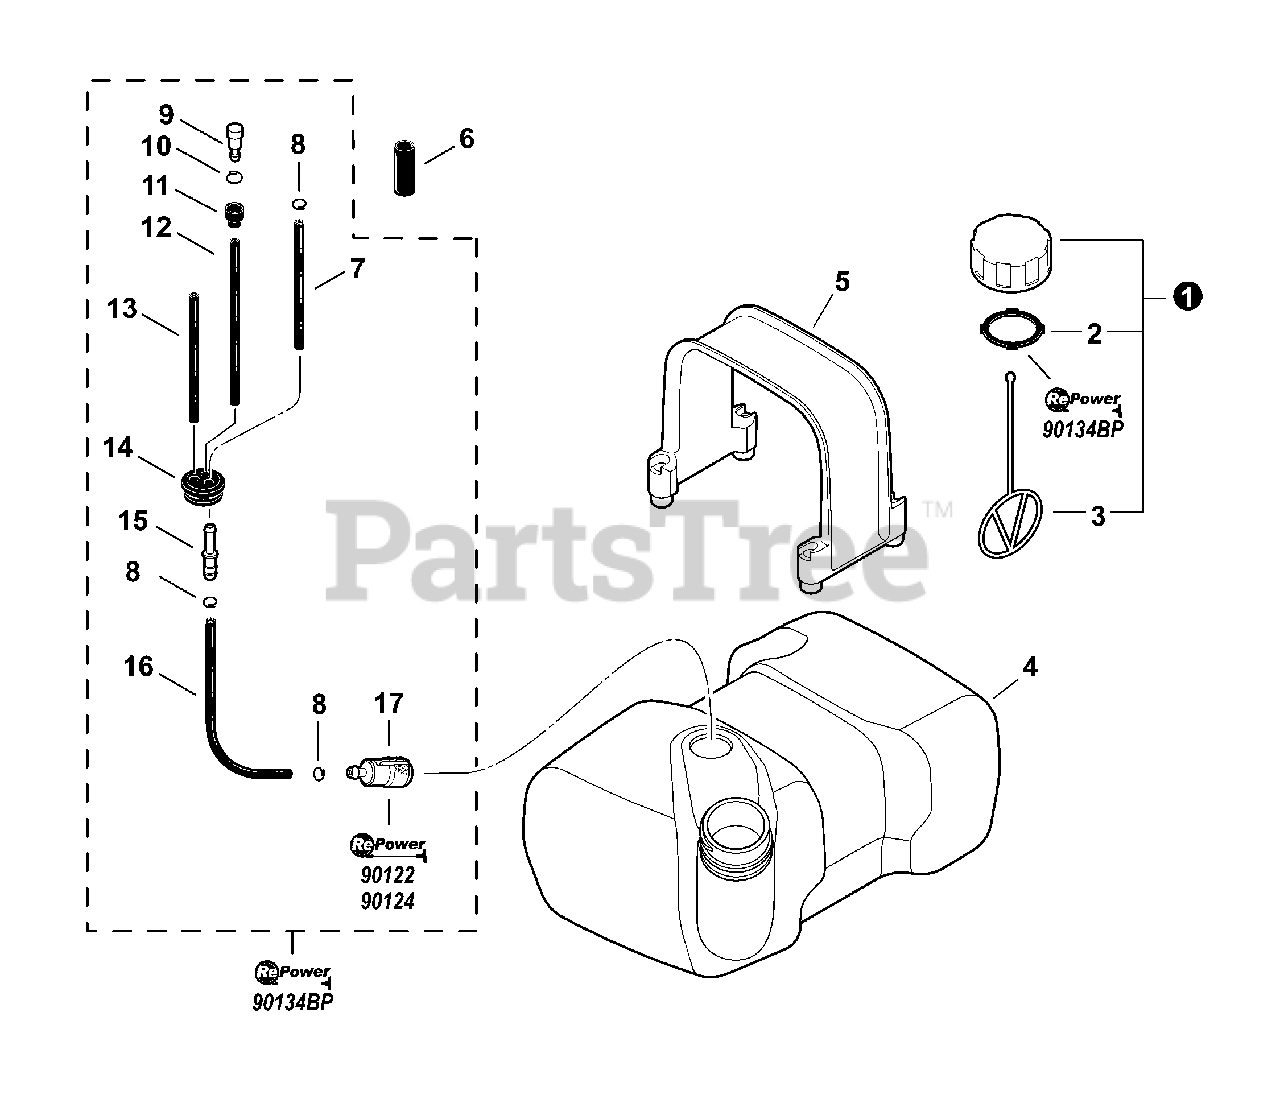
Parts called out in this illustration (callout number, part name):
1	CAP ASSY, FUEL
2	GASKET, FUEL CAP
3	CONNECTOR, CAP L= 100 MM
4	TANK, FUEL
5	RETAINER, FUEL TANK
6	TUBE, FUEL LINE 16×18×L40
7	PIPE, FUEL 3×5×135L BLACK
8	CLIP Ø6
9	VENT ASSY
10	CLIP Ø6.5 MM
11	HOLDER, VENT
12	PIPE, FUEL 3×6×130 BLACK
13	PIPE, FUEL 2.4×5×200 BLACK
14	GROMMET, FUEL
15	CONNECTOR, PIPE Ø5ר3.5
16	PIPE, FUEL 3×5×105L BLACK
17	FILTER, FUEL 125-528
